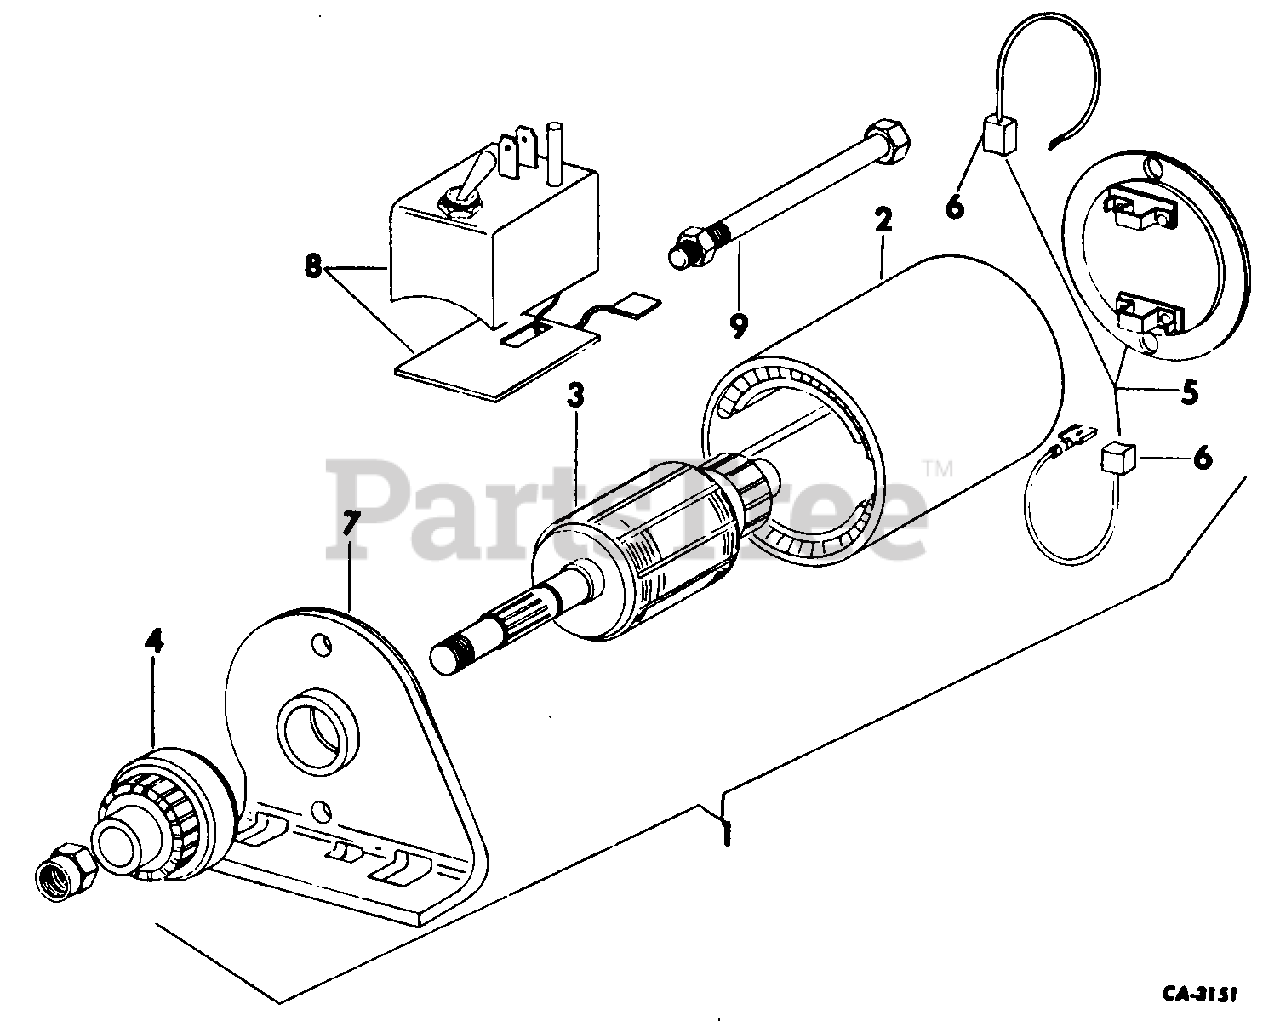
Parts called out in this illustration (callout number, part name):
1	START MOTOR ASSY
1	MOTOR & DRIVE ASSY
2	HOUSING, STARTER
3	ARMATURE
4	DRIVE, STARTER
4	DRIVE ASSY
5	CAP ASSY, COMMUTATOR END
6	BRUSH, KIT
7	CAP DRIVE END
7	SCREW, 5/16-18 X 11/16 HEX SEM
8	RECTIFIER & BRUSH
9	SCREW, WASHER & NUT
9	BOLT. THRU
